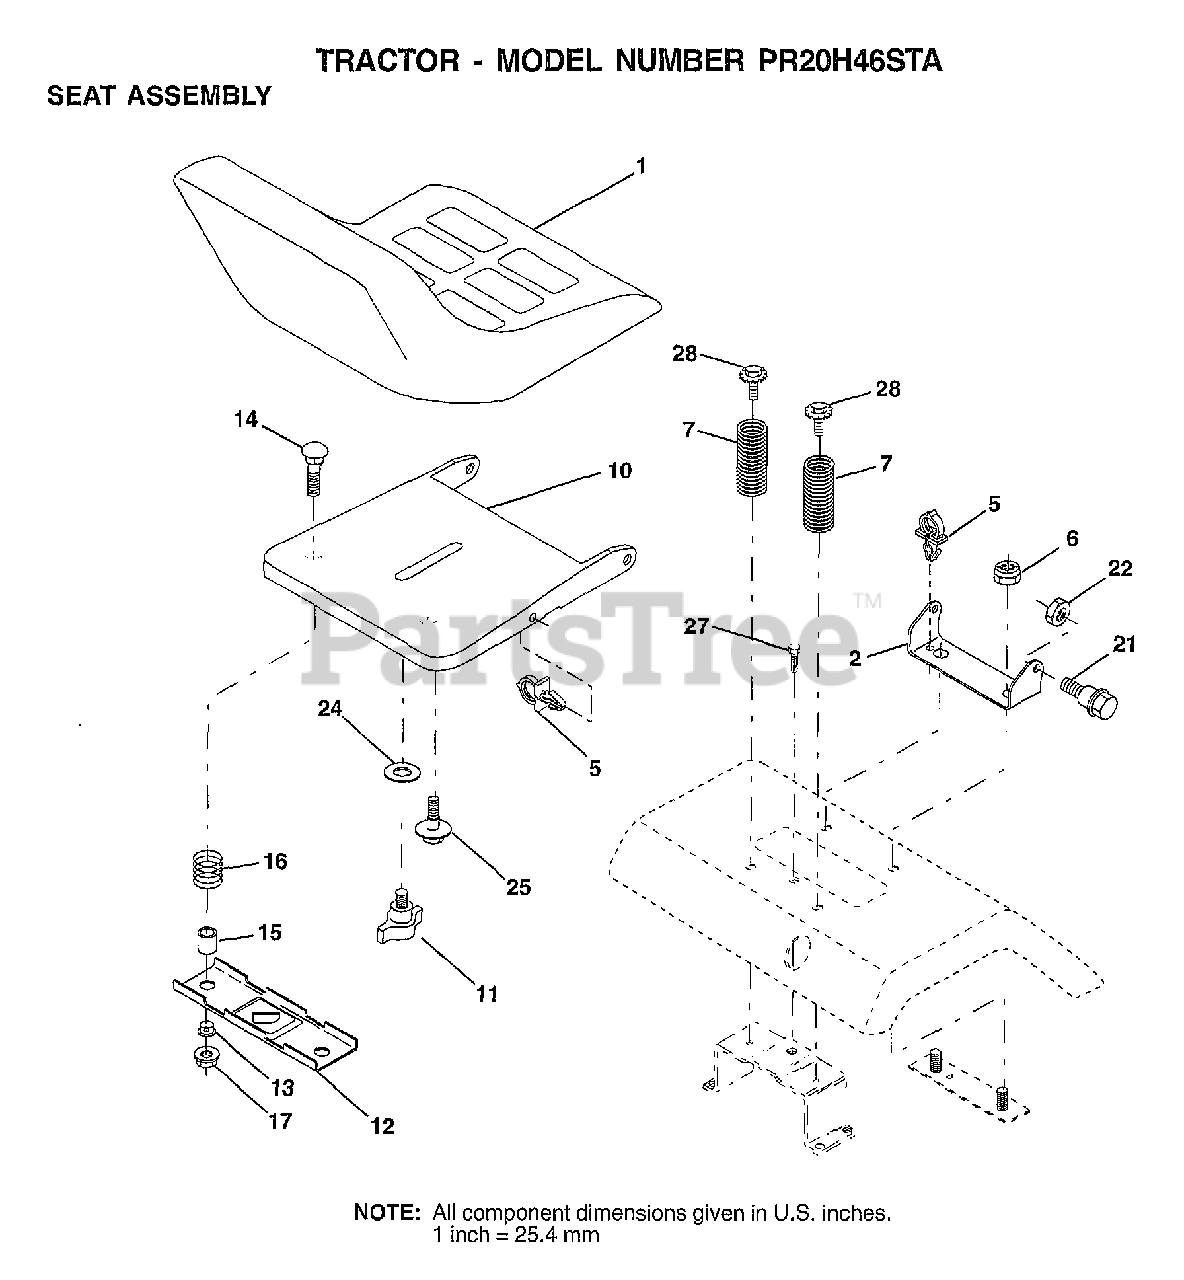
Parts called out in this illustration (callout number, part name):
1	SEAT
2	BRACKET PVT SEAT
5	CLIP.PUSH-IN.HING
6	NUT
7	SPRING COMPRESSIO
10	PAN-SEAT
11	KNOB.SEAT.ADJ.WINGNUT
12	BRKT SWITCH
13	BUSHING
14	BOLT-RD HD SQ NK
15	SPACER SPLIT
16	SPRING COMPRESSED
21	BOLT
22	NUT
24	WASHER
25	"BOLT,SHOULDER"
27	SCREW LT
28	BOLT
